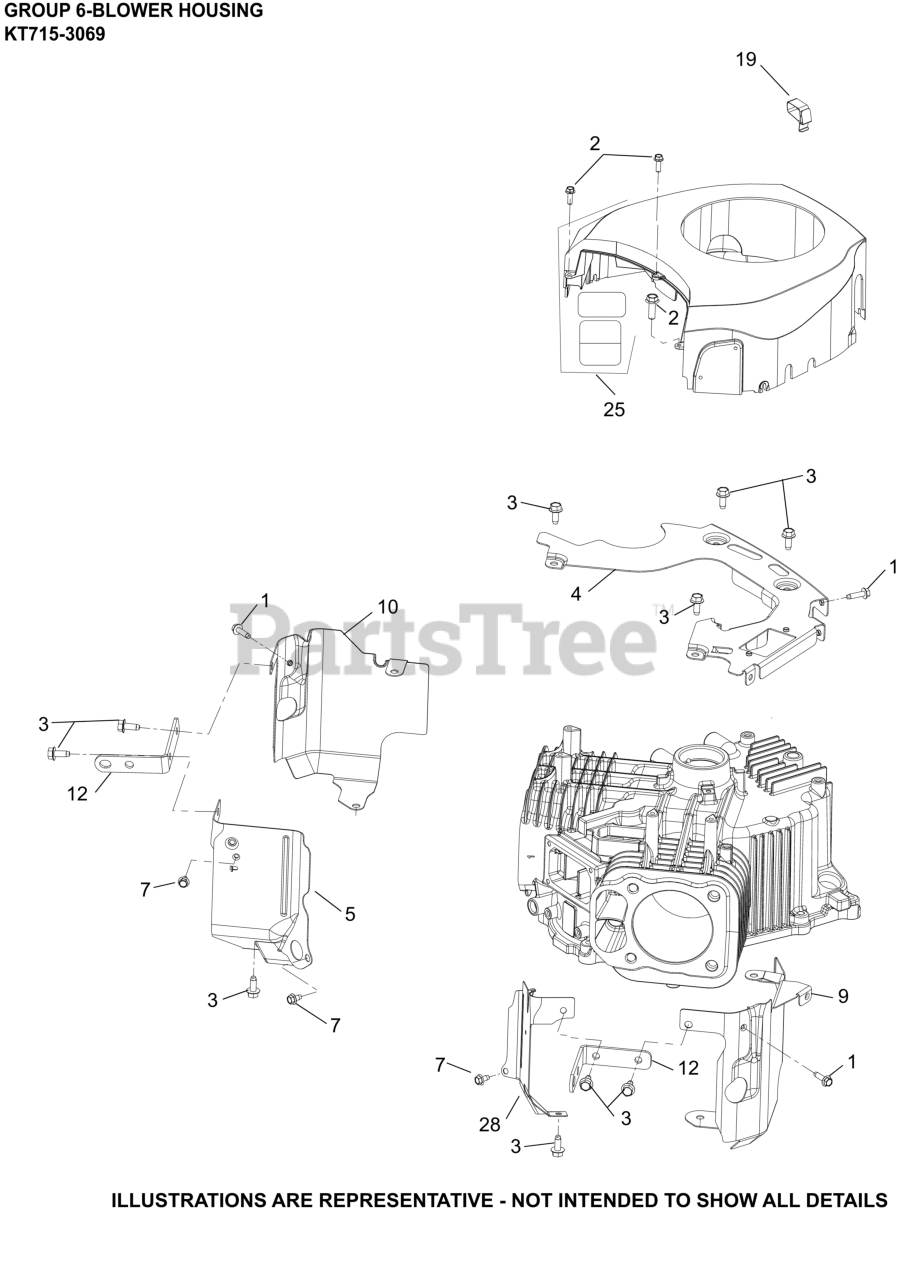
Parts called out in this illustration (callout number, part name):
1	SCREW, THD FRM-USE 25 086 473-S
2	SCREW, HI-LOW
3	SCREW, THREAD FORMING
4	PLATE, BACKING
5	BAFFLE, VALLEY #1
7	SCREW, THREAD FORMING
9	BAFFLE, LEFT BARREL
10	BAFFLE, RIGHT BARREL
12	STRAP, LIFTING
19	CLIP, BLOWER HOUSING
25	KIT, BLOWER HOUSING
28	BAFFLE, VALLEY #2
